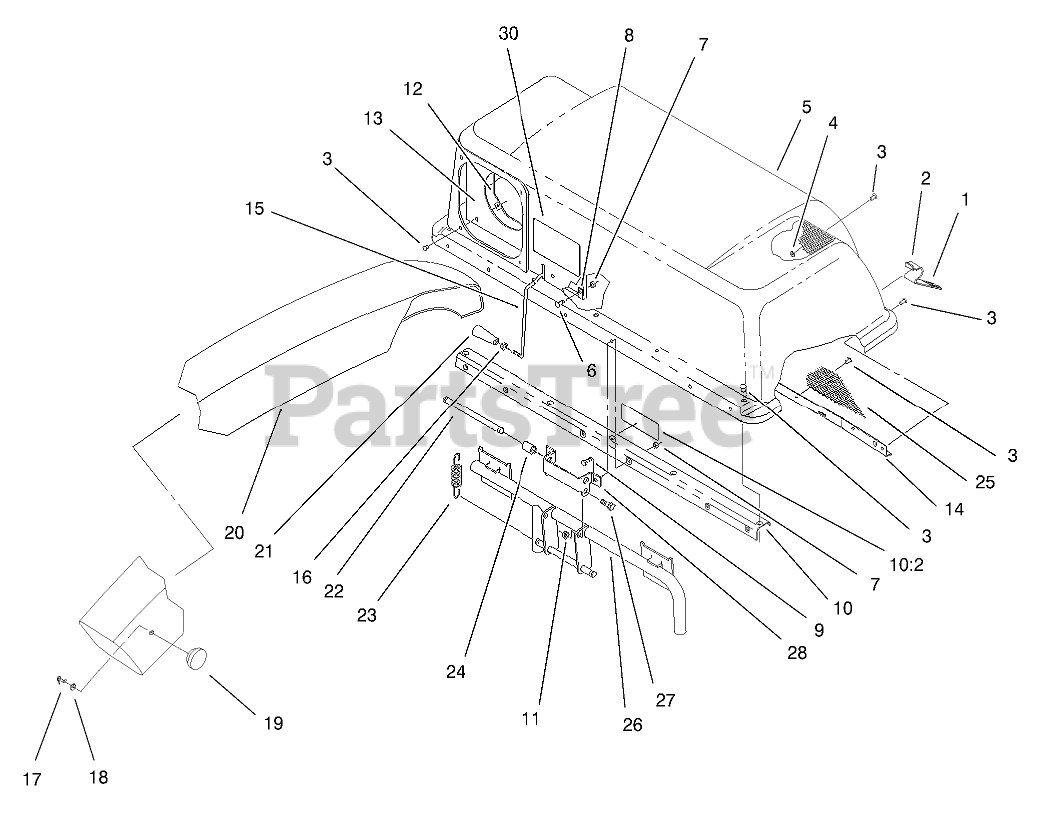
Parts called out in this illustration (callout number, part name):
2	LATCH-BAGGER, TOP
3	RIVET-BLIND
4	WASHER-FLAT
5	TOP-BAGGER
6	SCREW-HH
7	NUT-LOCK, NI
8	CLAMP
9	SCREW-HH
10	STIFFENER ASM
10:2	DECAL-CAUTION
11	NUT-LOCK, NI
12	CLAMP-SEAL
13	SEAL-CHUTE
14	SUPPORT-SCREEN
15	FEELER-FILL, BAG
16	NUT-JAM
17	SCREW-PPHTF
18	WASHER-PLAIN
20	Chute-Discharge
21	HANDLE-TAPERED
22	PIN-SPRING
23	SPRING-EXTENSION
24	Spacer
25	SCREEN-BAGGER
26	FRAME ASM
27	SCREW-HH
28	Hinge-Bag, Top
30	DECAL
